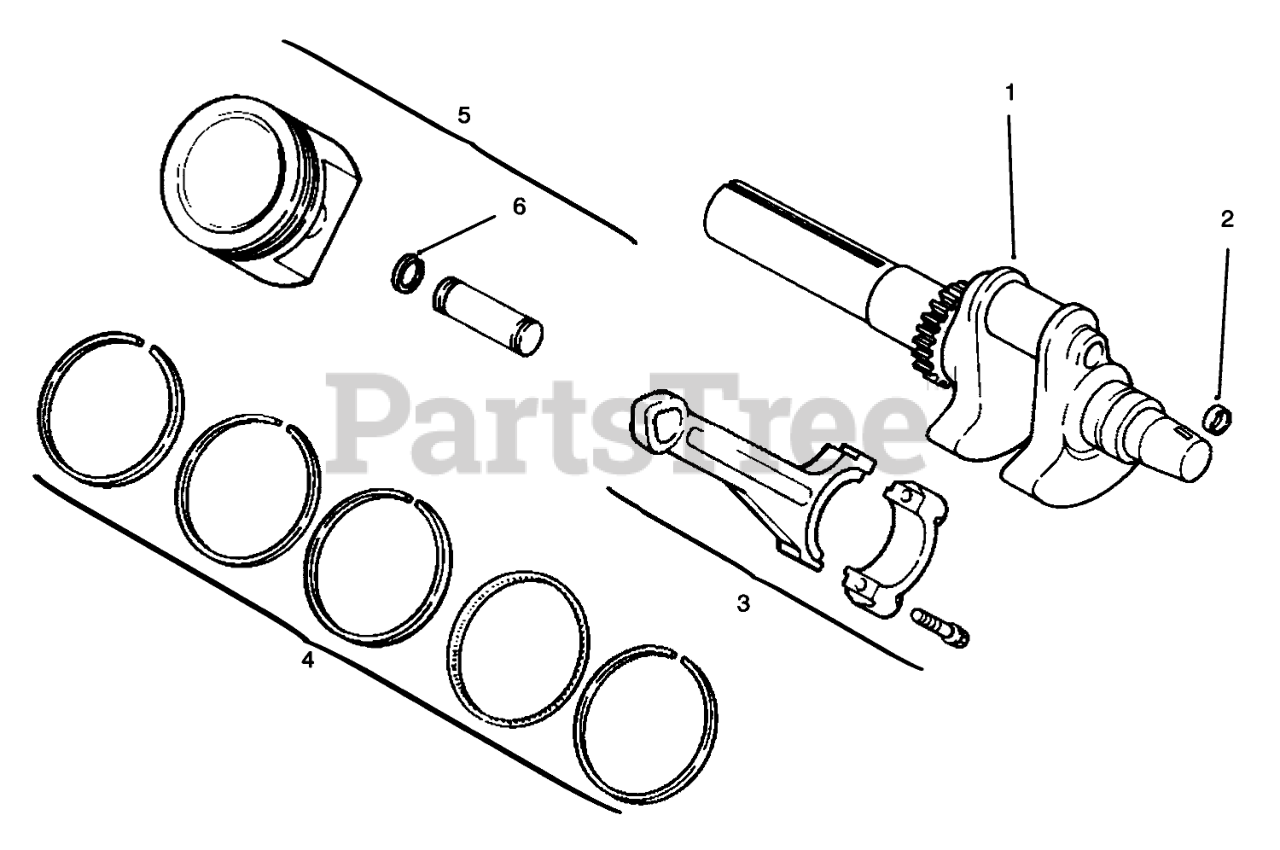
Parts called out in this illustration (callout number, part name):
1	Crankshaft
2	Plug
3	Rod-Connecting (Std)
4	Set-Ring (Std)
5	Piston w/Ring Set (Std.) (Incl. Ref. # 4-6)
6	Retainer-Piston Pin
